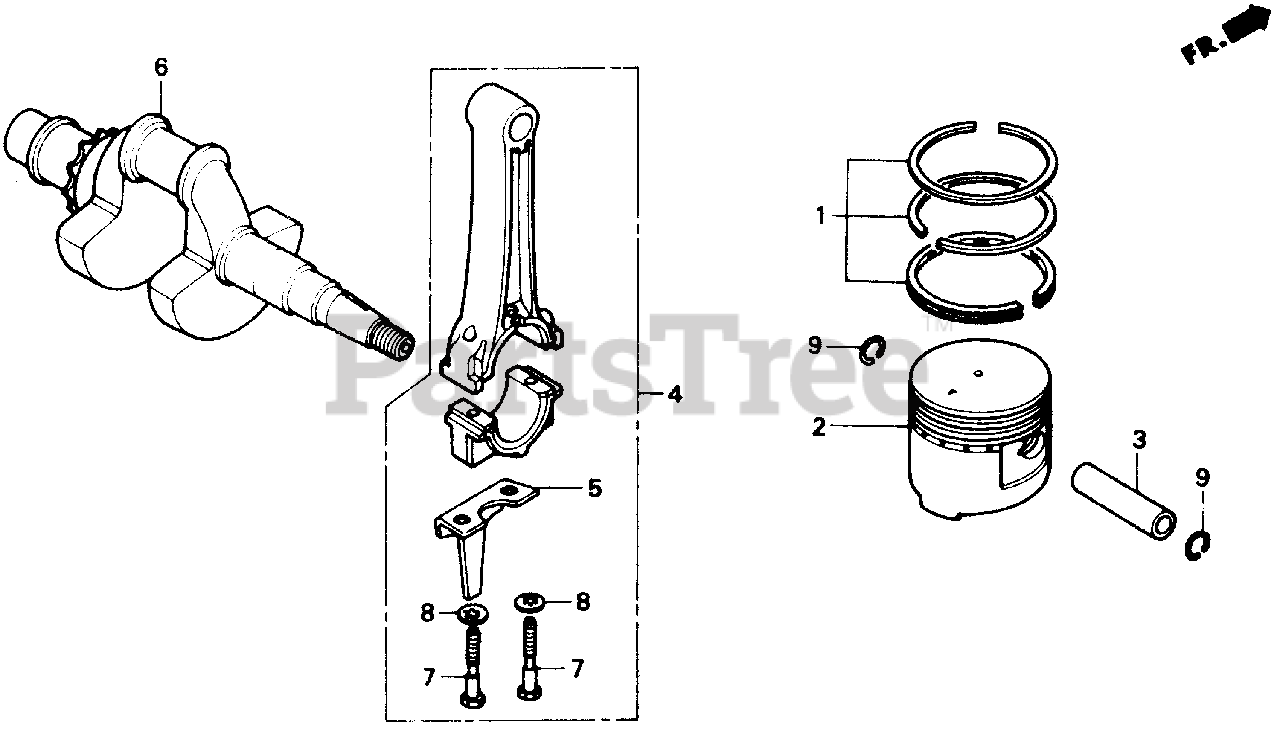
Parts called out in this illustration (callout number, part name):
1	RING SET, PISTON (STD)
1	RING SET, PISTON (OS 0.25)
1	RING SET, PISTON (OS 0.50)
1	RING SET, PISTON (0.75) (OS)
2	PISTON (STD)
2	PISTON (OS 0.25) (OS)
2	PISTON (OS 0.50) (OS)
2	PISTON (0.75) (OS)
3	PIN, PISTON
4	ROD ASSY., CONNECTING
5	DIPPER, CONNECTING ROD
6	CRANKSHAFT
7	BOLT, CONNECTING ROD (7MM)
8	WASHER, LOCK (7MM)
9	CLIP, PISTON PIN (15MM)
